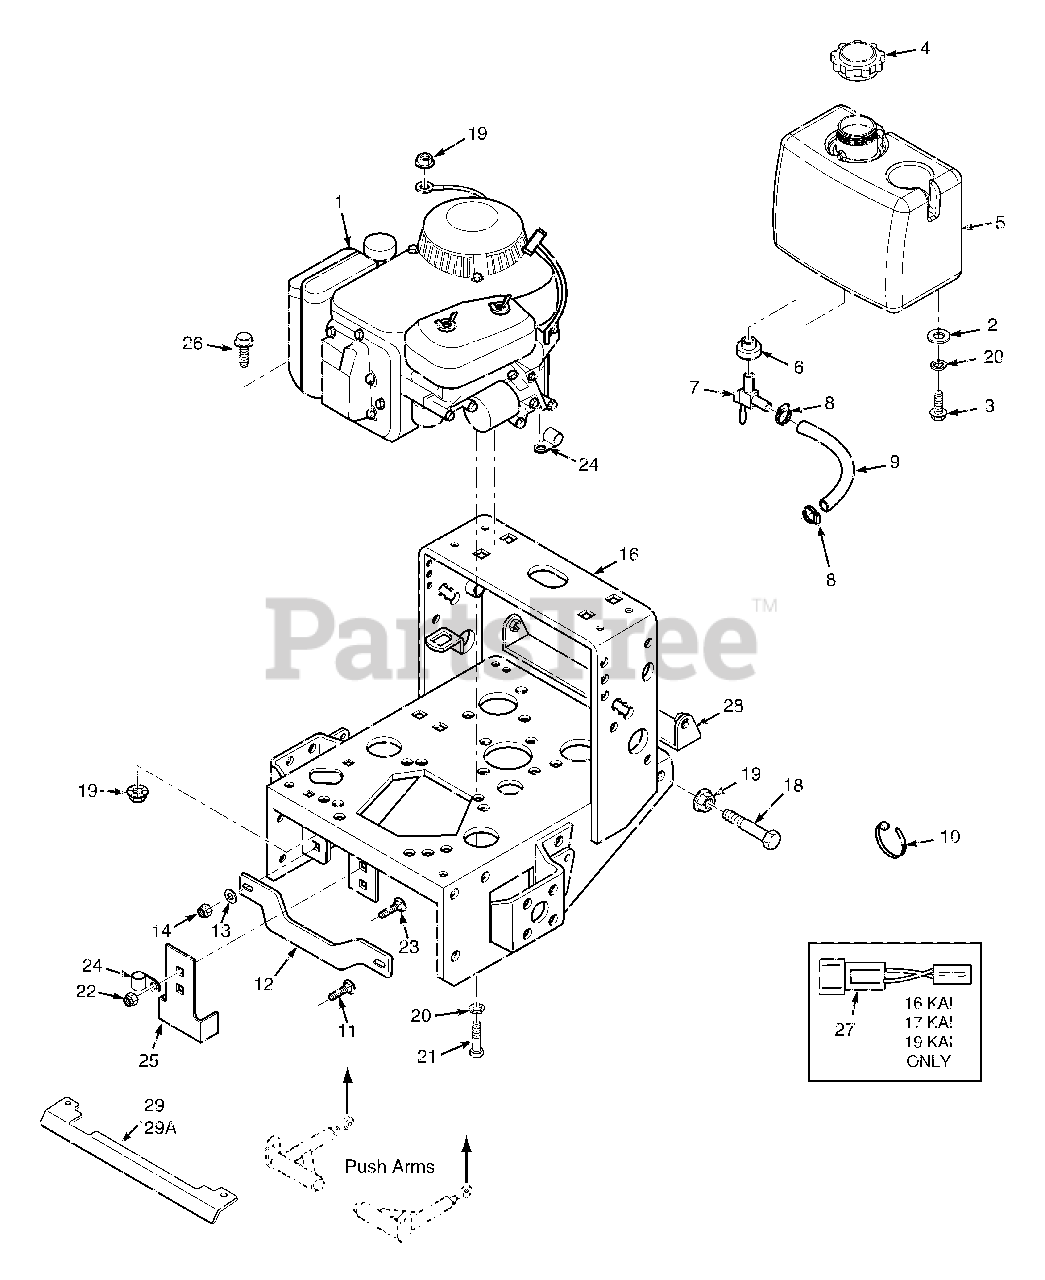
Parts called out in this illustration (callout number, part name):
1	Engine, 16KAI Kawasaki
2	Flatwasher, 5/16 (.375 x .875 x .083)
3	Capscrew, 5/16-18 x 1" Hex Head
4	Cap, Fuel Tank
5	Fuel Tank Assy.
6	Bushing
7	Valve, Fuel Shut-off
8	Clamp, Fuel Hose
9	Fuel Hose, 1/4 ID x 18"
10	Cable Tie
11	Carriage Bolt, 3/8-16 X 1-1/4"
12	Brace
13	Flat Washer .391 x .938 x .105
14	Nut, 3/8-16 Elastic Stop
15	Nut, 1/4-20 Elastic Stop
16	Engine Deck, 16" Wide, w/decals
17	Bolt, 1/4-20 x 1-1/4" Carriage
18	Bolt, 5/16-18 x 2" Hex Head
19	Nut, 5/16-18 Serr. Flange
20	Lock Washer 5/16"
21	Bolt, 5/16-18 x 1" Serrated Flange Hex Head
22	Nut, 5/16-18 Elastic Stop
23	Carriage Bolt, 5/16-18 x 1"
25	Clutch Bracket
26	Cap Scrw, 5/16-18 x 1.50" Sr. Flg
27	Wire Harness Adapter
28	Pulley Guard, 16" Frame
29	Heatshield
29A	Heatshield
